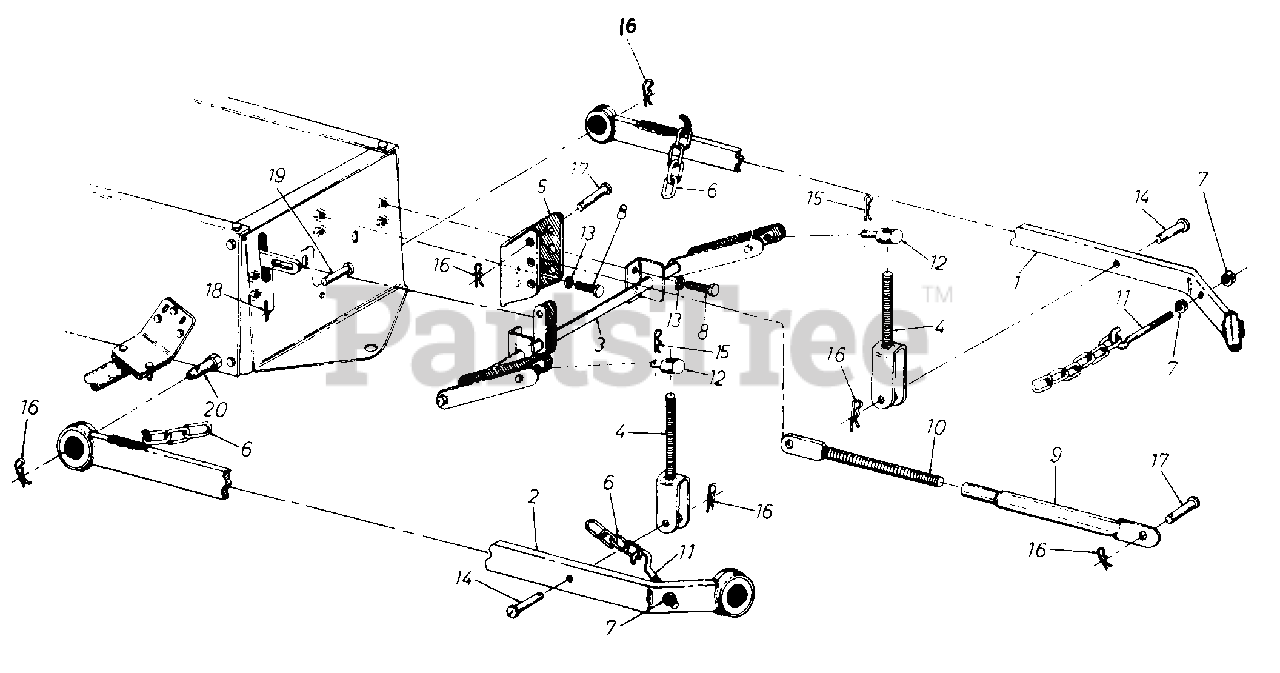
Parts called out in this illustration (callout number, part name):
1	Draft Bar Assembly - R.H.
2	Draft Bar Assembly - L.H.
6	Chain 20 links
7	Hex Cent. L.-Nut 7/16-14 Thd.
8	Hex Bolt 5-3/8-16 x 1 Lg. Grade 5
10	Clevis Screw
11	Hitch Chain Hook
12	Clevis Pin
13	L.-Wash. 3/8" I.D.*
14	Clevis Pin 5/8 Dia. x 1.66 Lg.
15	Hairpin
16	Hairpin
17	Clevis Pin 5/8 Dia. x 2.4 Lg.
18	Cotter Pin 1/8 Dia. x 1-1/4 Lg.*
19	Clevis Pin
20	Link Clevis Pin
